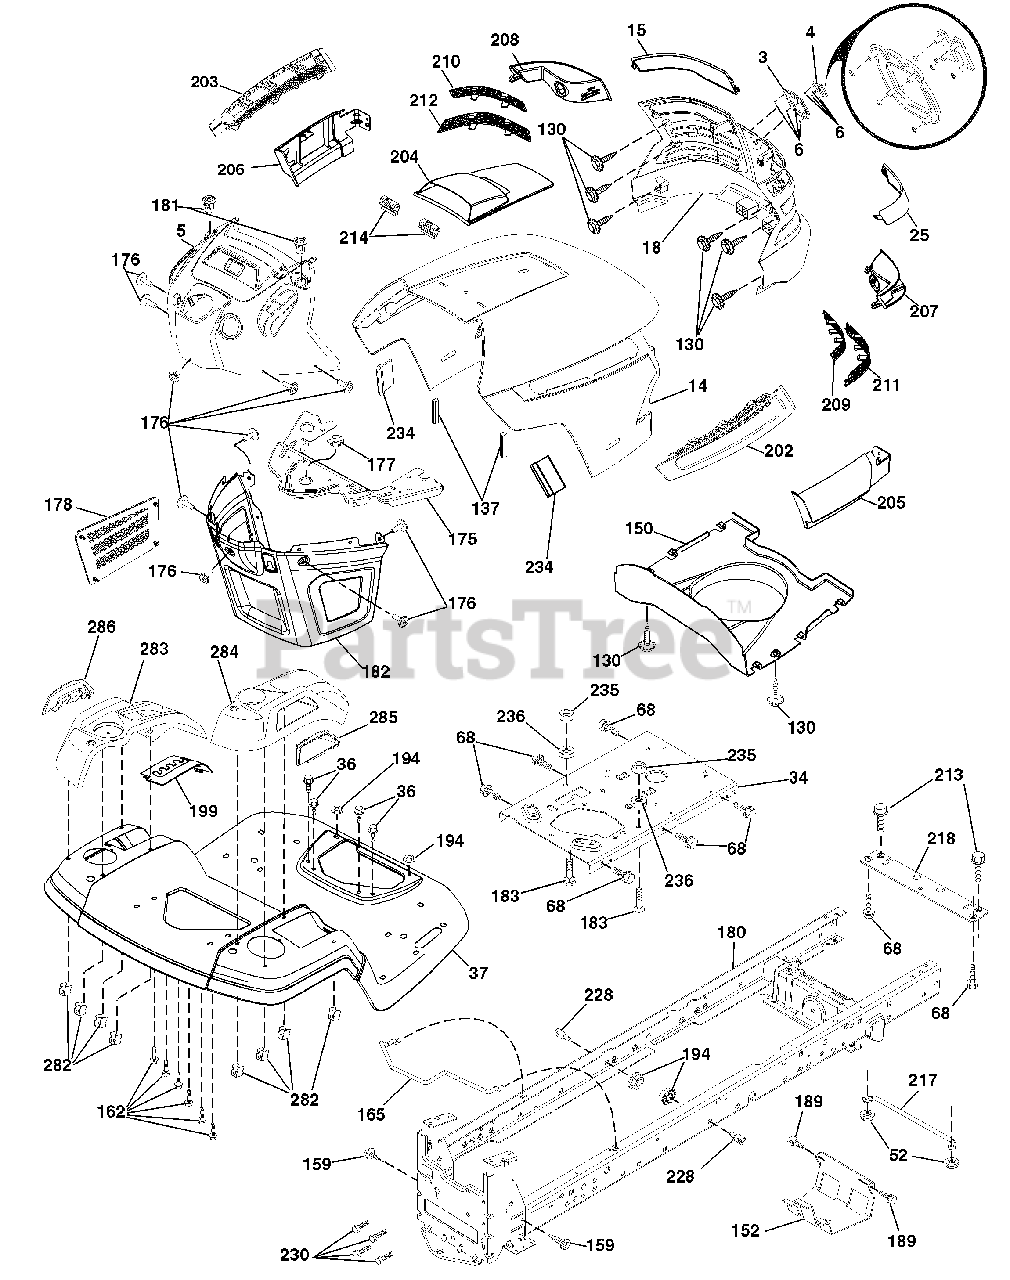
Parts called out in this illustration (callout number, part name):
3	Trim, Husq.
4	Logo
14	Hood
18	Grille/Lens Asm.
34	Plate Engine
36	Screw 5/16-18 x 3/4
37	Fender
52	Nut Lock 5/16-18
68	Screw Thdrol 5/16-18 x 1/2
130	Screw 10 x .750 BOS Thread
137	Bumper Dash
152	Shield Browning
157	Screw 3/8-16 x 3/4
175	Crossmember
176	Screw 10-24 x 5/8
177	Bushing Steering
178	Cargo Net Asm.
180	Chassis
181	Bushing Mtg. Fender Crgo
182	Dash Lower
183	Bolt Fin Hex 5/16-18 unc x 1-1/4
189	Screw 5/16-18 x 3/4
194	Nut Lock Hex Flange 5/16-18
199	Plate Deck Lift
202	Vent Side Hood RH
203	Vent Side Hood LH
204	Vent Top Hood
205	Skirt Hood Side RH
206	Skirt Hood Side LH
209	Insert Hex Top RH
210	Insert Hex Top Lh
211	Insert Hex Bottom RH
212	Insert Hex Bottom LH
213	Bolt 5/16-18 x 3/4
214	Clip Retainer Tinner
218	X-Piece Hood Stop
228	Stud Fastner
230	Bolt Shoulder 5/16-18
234	Bumper Hood
235	Spacer Fender
236	Nut Lock 5/16-18 UNC
282	Clip Retainer Console
283	Console Deck Lift
284	Console Shift
285	Console Insert RH
286	Console Insert LH
287	Screw 1/4-20 X 3/8
